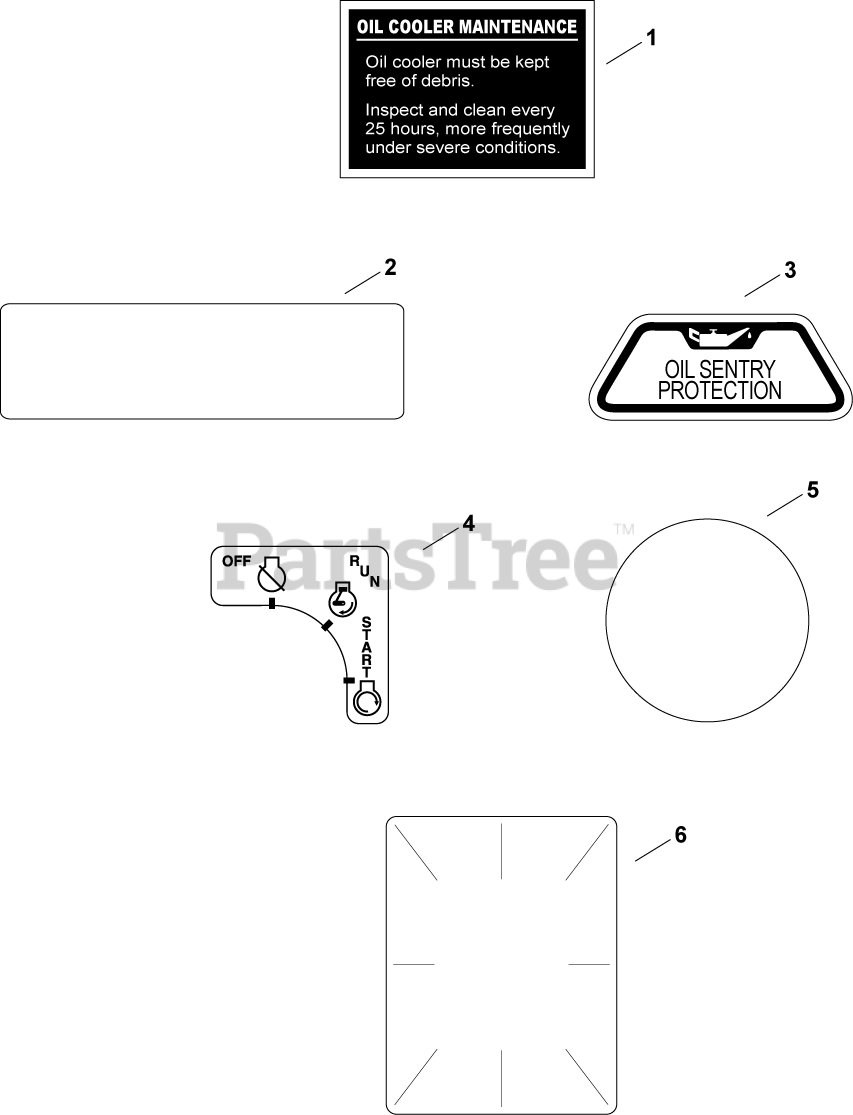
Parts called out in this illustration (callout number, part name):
1	DECAL, OIL COOLER - (#DSC)
2	DECAL, 25 HP - DISCONTINUED
3	DECAL, OIL SENTRY - (#DSC)
4	DECAL, KEY SWITCH
5	DECAL, GRASS SCREEN USE 24 113 499-S
6	DECAL, CLEAR LAMINATE USE 25 113 70-S
